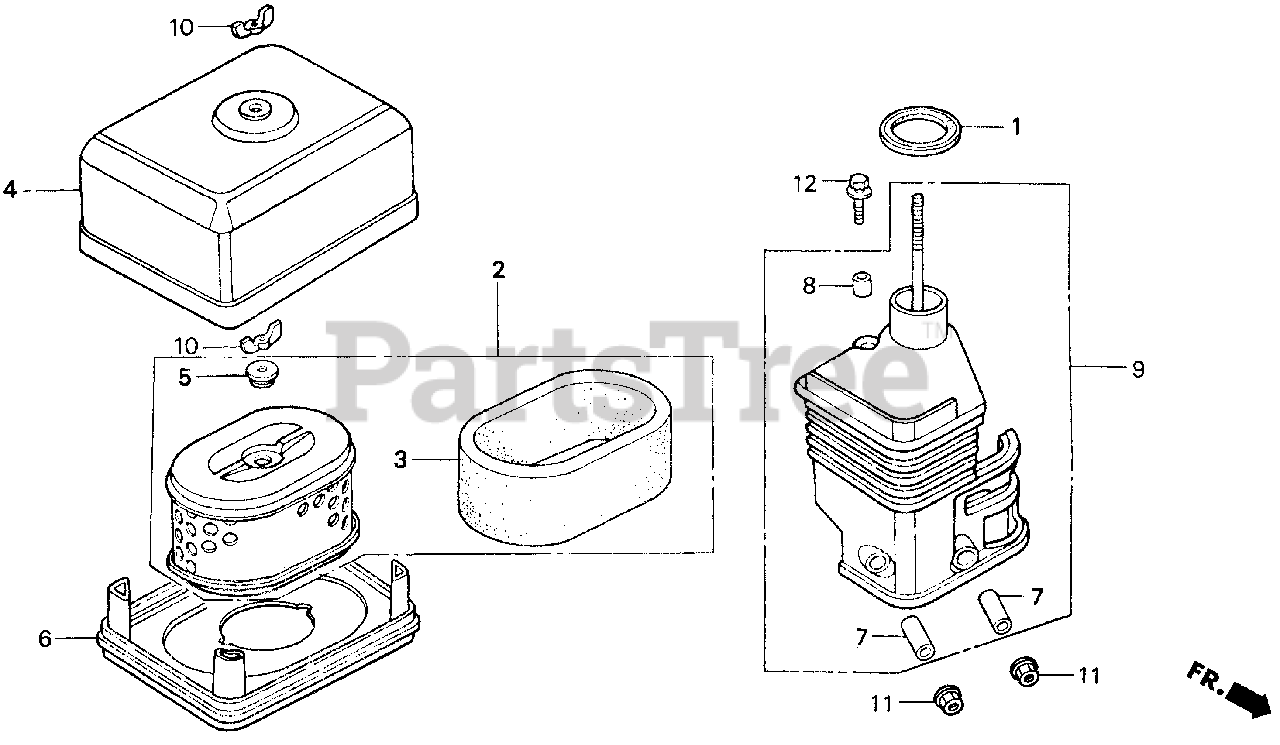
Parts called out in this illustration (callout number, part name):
1	GASKET, ELBOW
2	ELEMENT, AIR CLEANER (DUAL)
3	FILTER (OUTER)
4	COVER, AIR CLEANER (DUAL)
5	GROMMET, AIR CLEANER
6	NOSE, MUFFLER
7	COLLAR, AIR CLEANER
8	COLLAR B, AIR CLEANER
9	ELBOW, AIR CLEANER
10	WINGNUT, TOOL BOX SETTING
11	NUT, FLANGE (6MM)
12	BOLT, FLANGE (6X20)
